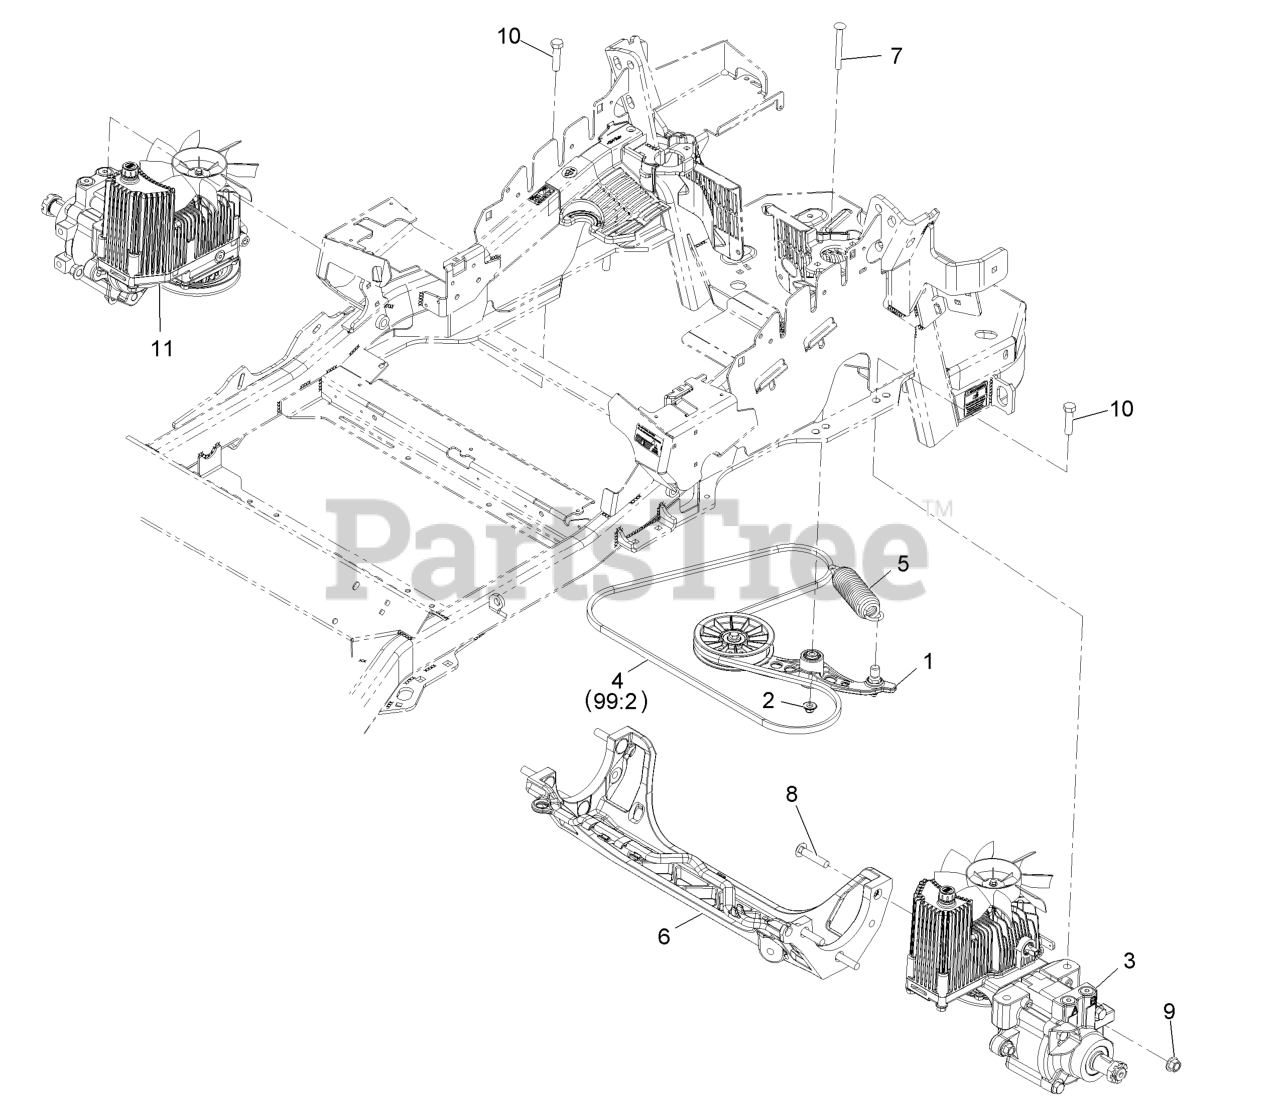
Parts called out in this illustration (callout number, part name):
1	PUMP IDLER ASM
2	Nut-Nyloc 3/8-16 Flg
4	BELT
7	BOLT-SHOULDER, CARRIAGE 3/8-16 X 3 1/2
8	SCREW-CARR
9	Nut-Lock 1/2-13
10	SCREW-HH
99:2	BELT
